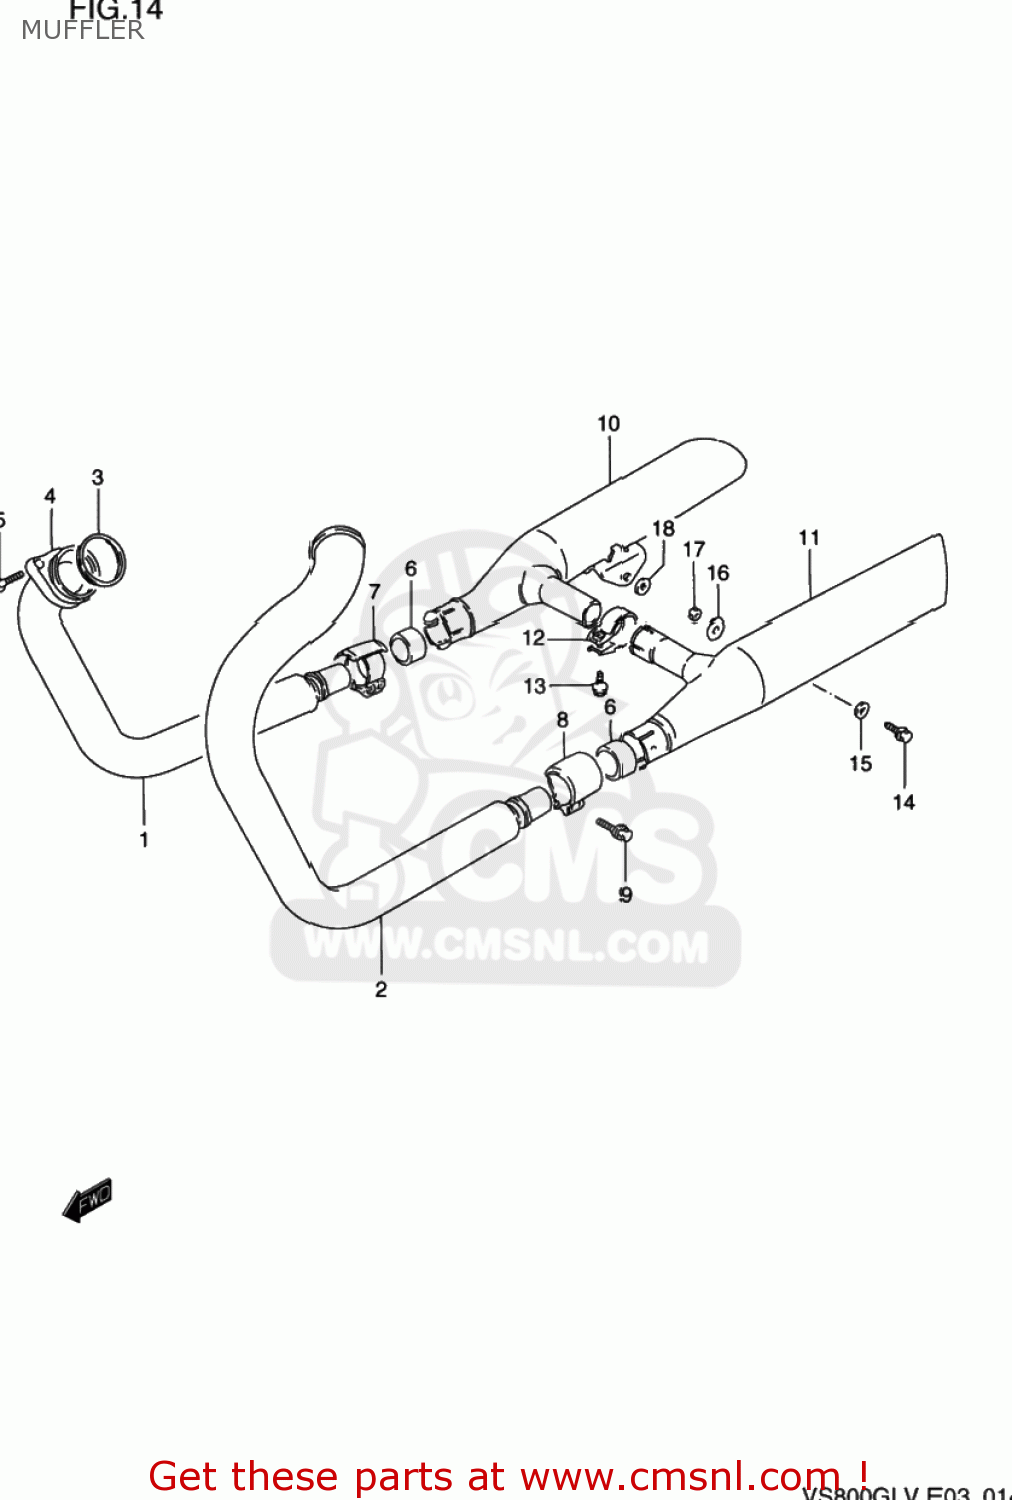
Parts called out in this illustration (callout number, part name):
1	PIPE,EXHAUST
2	PIPE,EXHAUST
3	GASKET,EXHAUST PIPE (NAS)
4	CLAMP,EXHAUST PIPE
5	BOLT(8X35)
6	CONNECTOR,EXHAUST PIPE
7	CLAMP,MUFFLER CONNECTOR,R
8	CLAMP,MUFFLER CONNECTOR,L
9	BOLT
10	BODY,MUFFLER,R
11	BODY,MUFFLER,L
12	CLAMP,EXHAUST COUPLER
13	BOLT
14	BOLT
15	WASHER
16	WASHER
17	NUT
18	WASHER (8.5X18X3.2)
